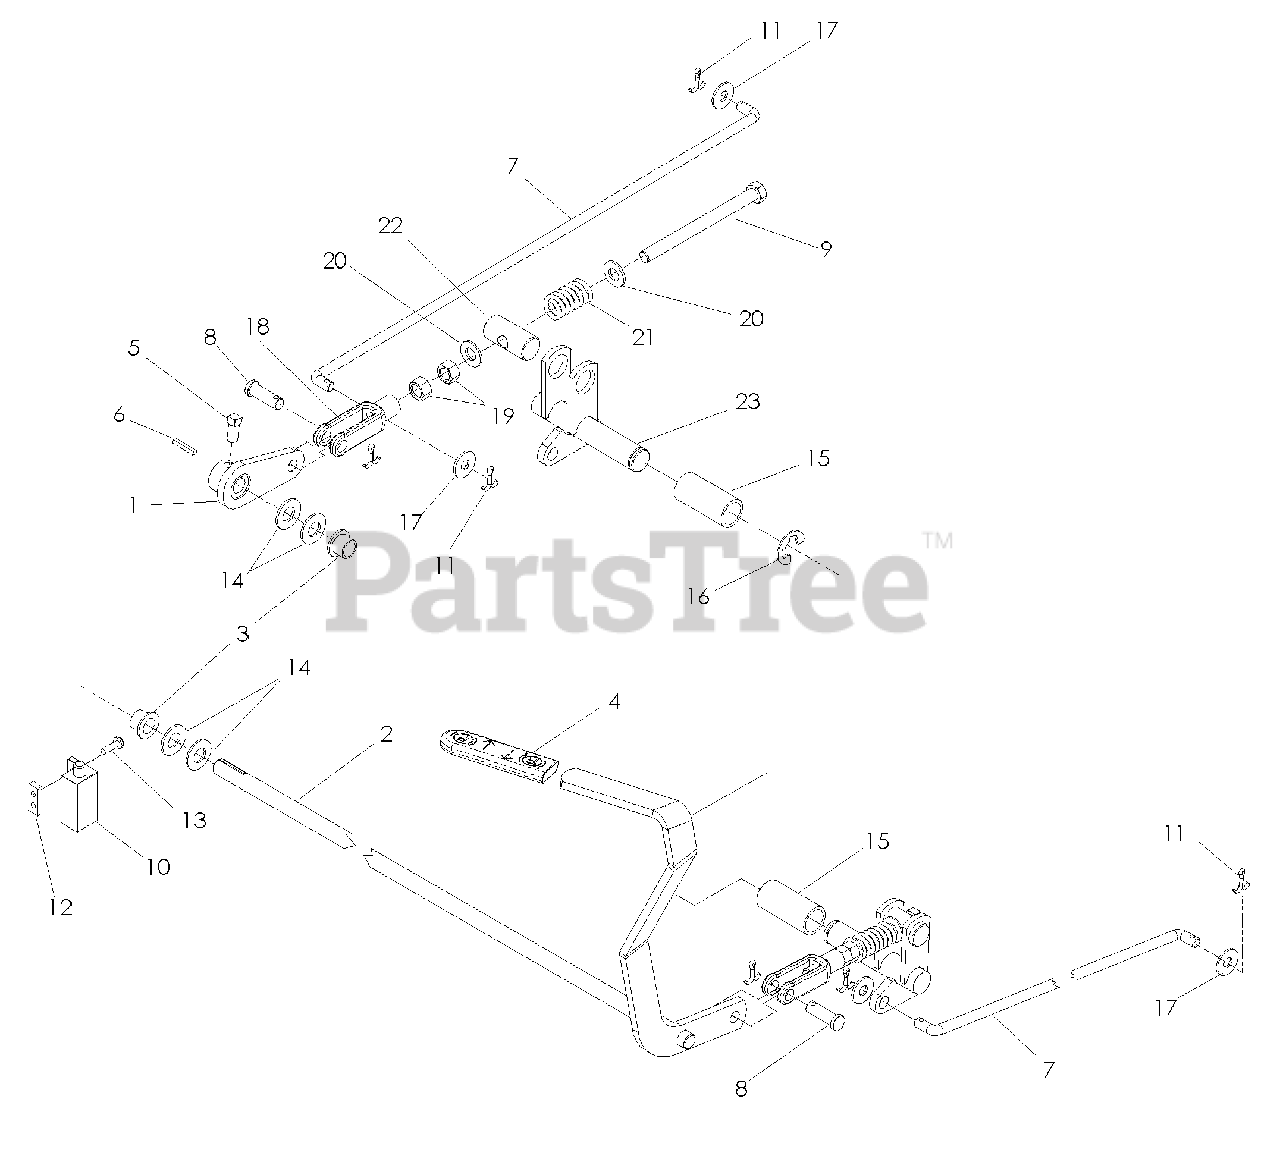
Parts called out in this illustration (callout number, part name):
1	BRAKE ARM WLDMT
2	BRAKE LEVER WLDMT
3	BRONZE BUSHING
4	GRIP, PARK BRAKE
5	SCREW 5/16-18 x 5/8 SQ HD
6	KEY 1/8 SQ x 7/8
7	BRAKE LINKAGE BAR
8	CLEVIS PIN
9	HCS 3/8-24 SPECIAL
11	PIN, COTTER 1/8 x 3/4
12	TAPPED PLATE
13	SCREW #10-24 x .625
14	WASHER, SPRING DISC 7/16
15	BRONZE BEARING
16	E-RING, 3/4
17	WASHER 5/16 STD FLT
19	NUT 3/8-24
20	WASHER 3/8 SAE FLT
22	TRUNION PIN
